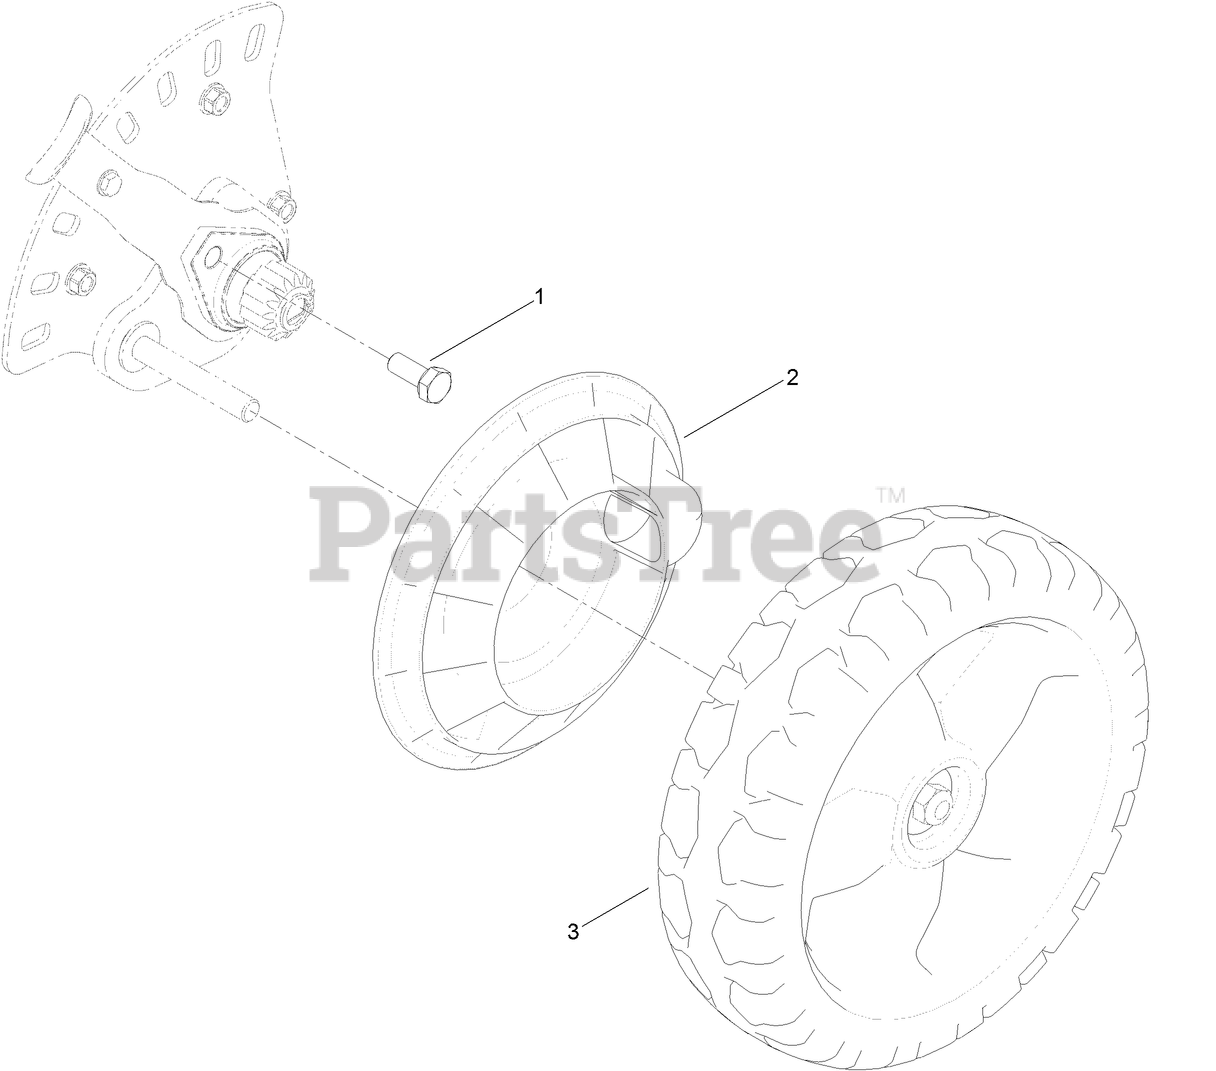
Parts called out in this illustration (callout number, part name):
1	SCREW-HH
2	COVER-WHEEL
3	9-INCH WHEEL ASM
